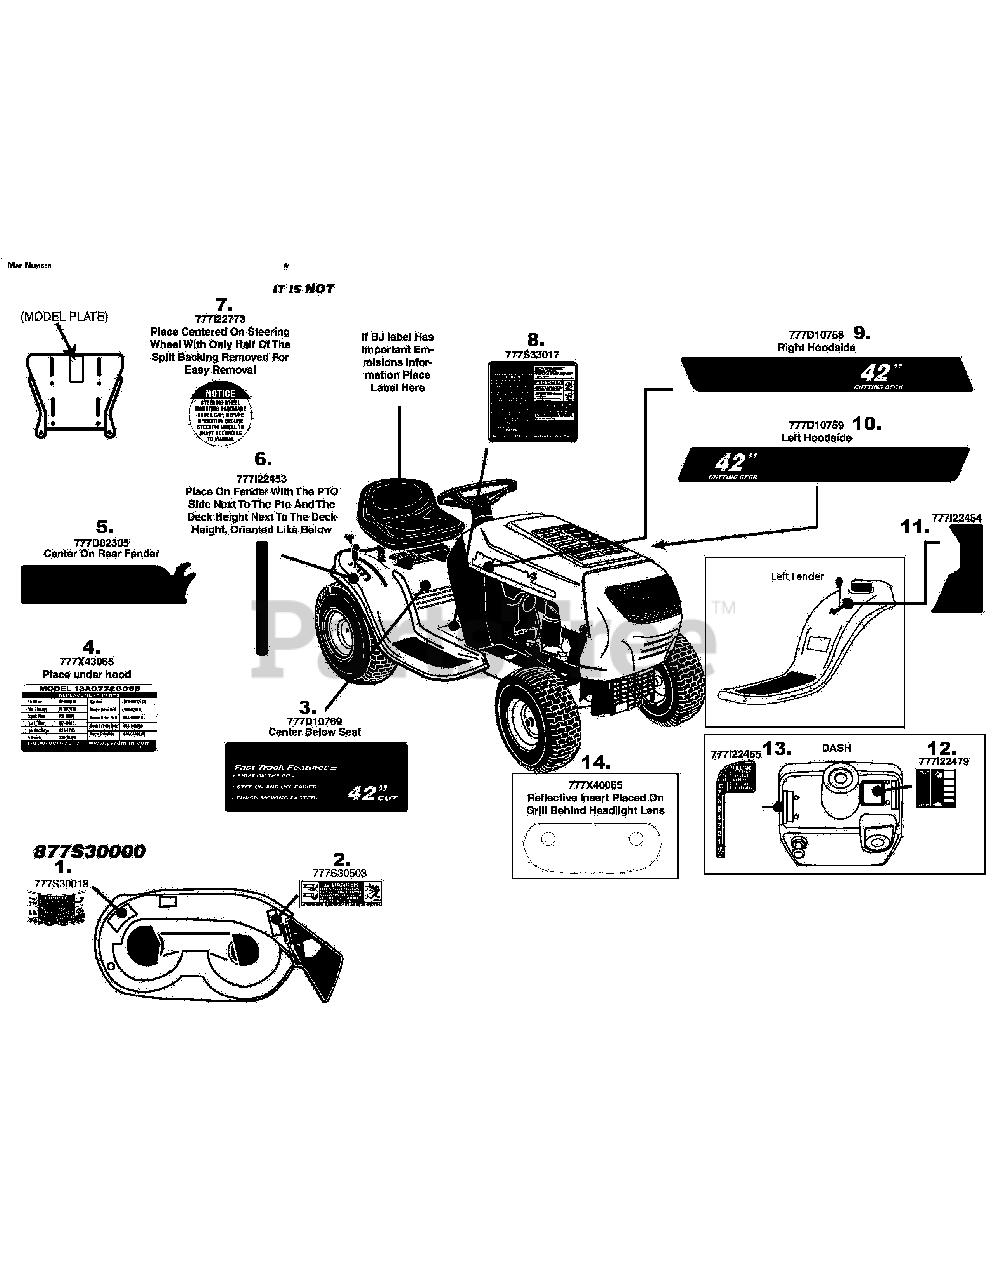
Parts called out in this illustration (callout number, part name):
1	LABEL-DECK SAFETY
2	LABEL-DANGER CHUTE
3	LABEL-RIDER RUNNING BOARD YARDMAN
4	LABEL-RIDER PARTS LIST YMAN 0772G
5	LABEL-REAR FENDER
6	LABEL:RIDER LT-5 FENDER
7	LABEL-RIDER:SECURE WHEEL
8	LABEL-LT 5 TRANS COVER NO OCR
9	LABEL-RIDER:HOOD YARDMAN RH
10	LABEL-RIDER:HOOD YARDMAN LH
11	LABEL:RIDER LT-5 FENDER
12	LABEL: RIDER LT-5 THRT/CHK
13	LABEL:RIDER LT-5 DASH
14	LABEL REFLECTOR
